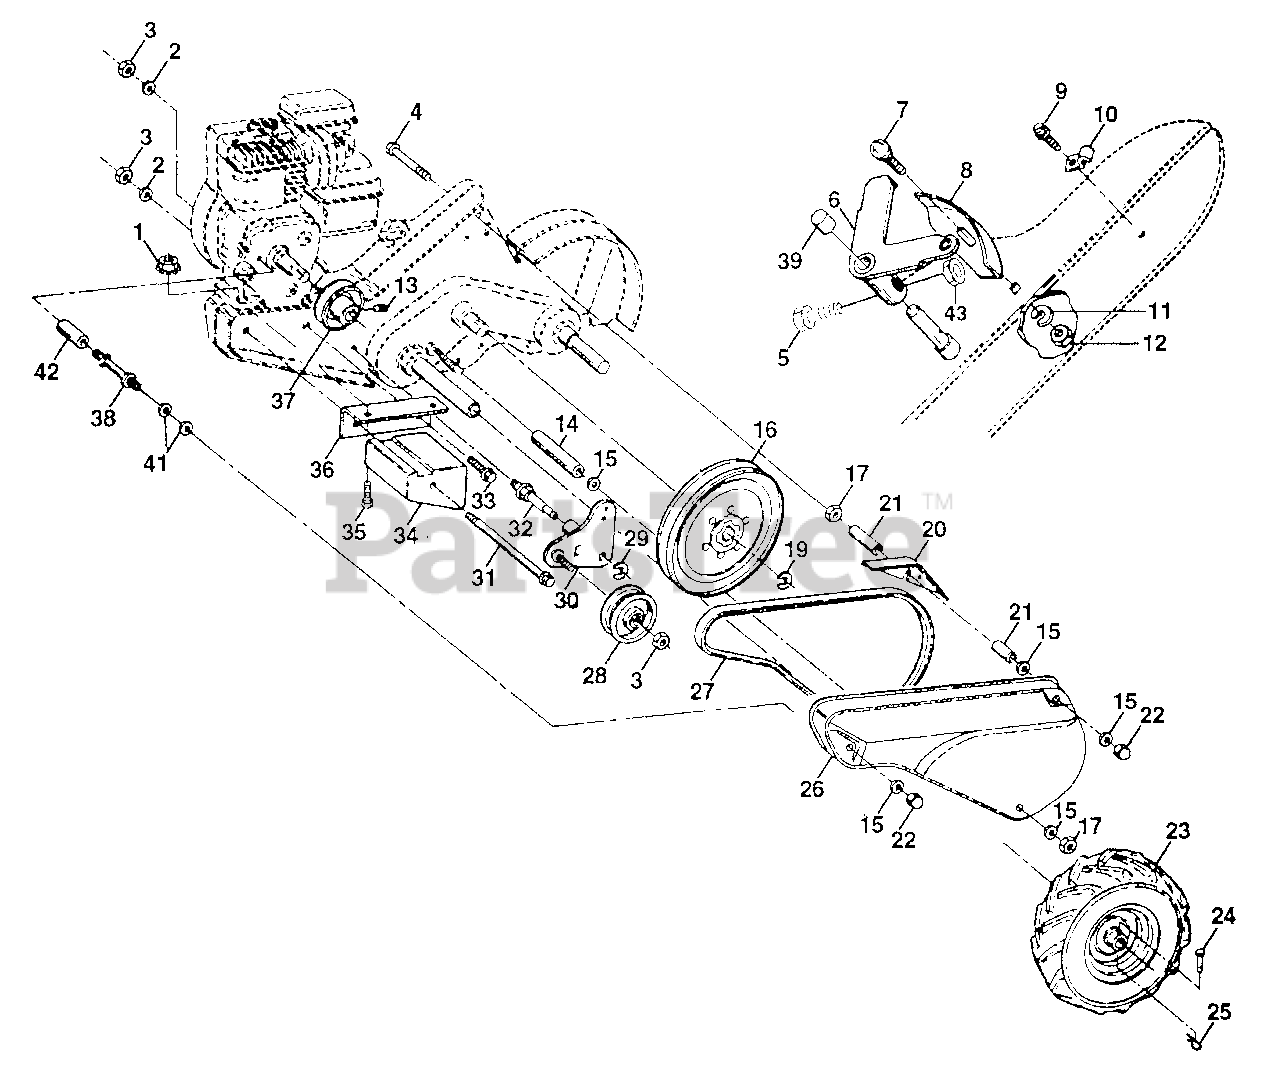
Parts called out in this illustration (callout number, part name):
1	Nut, Keps 5/16-18
2	Washer, Lock 3/8
3	Nut, Hex 3/8-16
4	Bolt, Hex 5/16-18 x 4-1/4
5	Screw Shift Lever
6	Lever, Shift
7	Bolt, Carriage 1/4-20 x 1/2 Gr. 5
8	Plate, Shift Indicator
9	Screw, Hex, Washer Head, Slotted #10-24 x 1/2 (AYP part number)
10	Clip
11	Washer, Lock 1/4
12	Nut, Hex 1/4-20
13	Screw, Set, Hex 5/16-18 x 3/8
14	Spacer, Split 0.327 x 0.42 x 2.68 (AYP part number)
15	Washer 11/32 x 11/16 x 16 Ga.
16	Sheave, Transmission
17	Nut, Hex 5/16-18
19	Ring, Retainer (AYP part number)
20	Guard, Pinch Point (AYP part number)
21	Spacer, Split 0.327 x 0.42 x 1.627
22	Nut, Cap 5/16-18 (AYP part number)
23	Tire
23	Rim (AYP part number)
23	Tire Valve (AYP part number)
24	Rivet, Drilled
25	Clip, Hairpin (AYP part number)
26	Guard, Belt (AYP part number)
27	Belt, V
28	Pulley, Idler (AYP part number)
29	Ring, Klip
30	Bracket, Idler (AYP part number)
31	Bolt, Hex 5/16-16 x 12 (AYP part number)
32	Shaft, Idler Arm (AYP part number)
33	Bolt, Hex 3/8-16 x 1
34	Counterweight, L. H. (AYP part number)
35	Bolt, Hex 5/16-18 x 1-1/2
36	Bracket, Reinforcement, L. H. (AYP part number)
37	Sheave, Engine
38	Bracket, Guard Belt
39	Cap, Plunger Blk
41	Washer 11/32 x 1 x 10 Ga.
42	Spacer
43	Nut Lock #10-24
